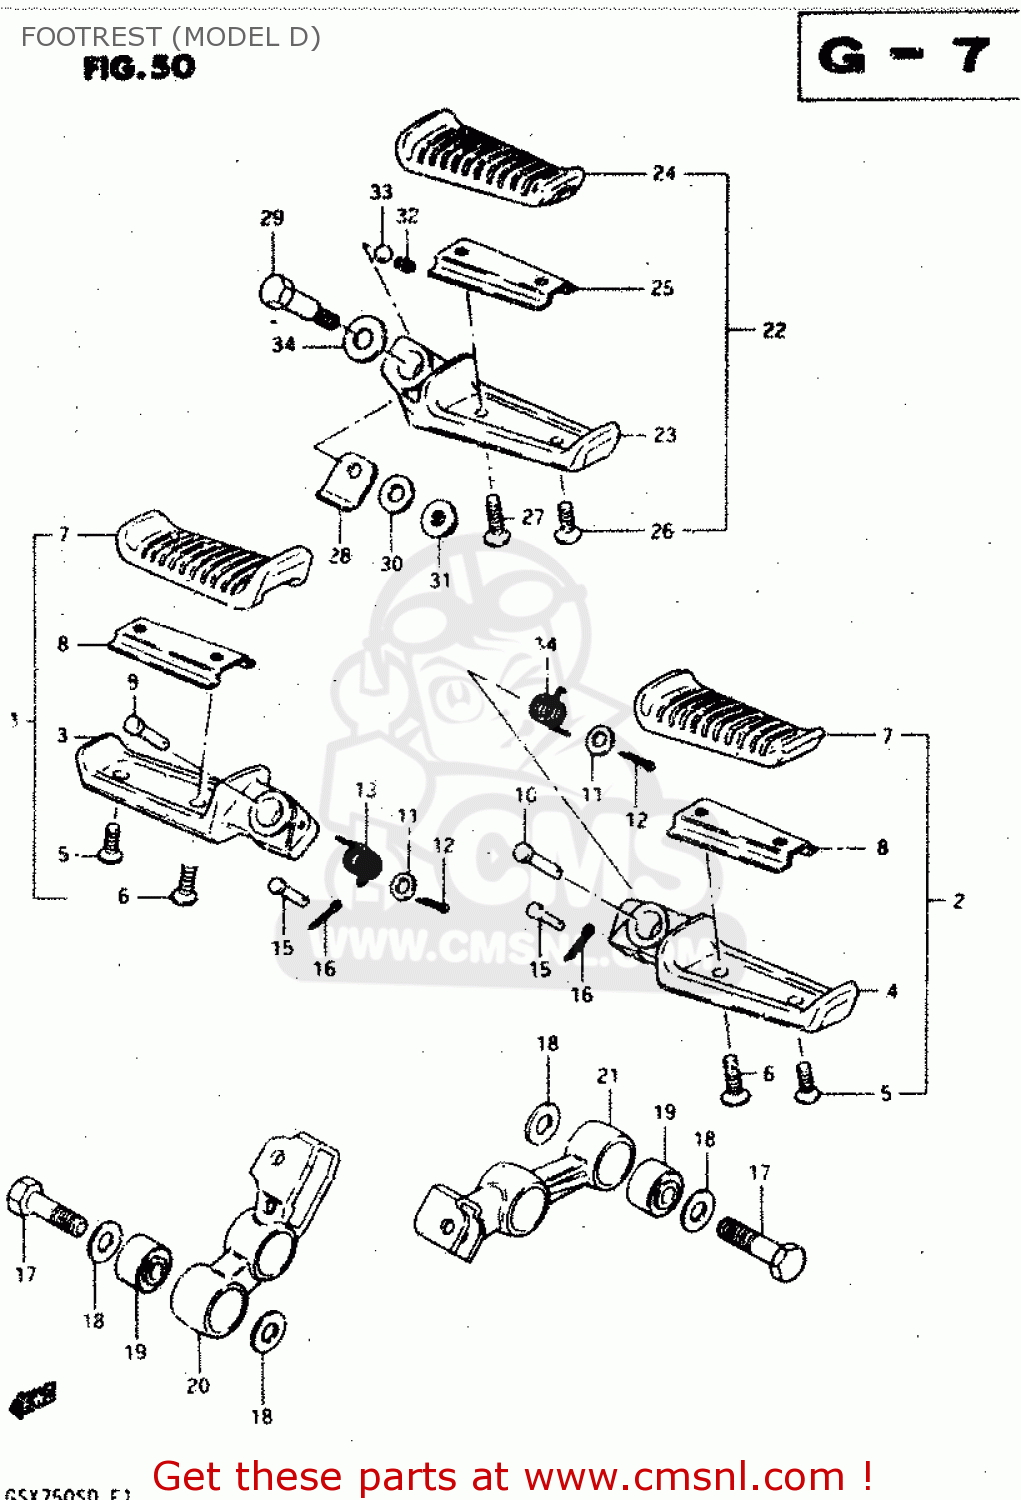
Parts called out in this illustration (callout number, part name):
1	FOOTREST ASSEMBLY,FRONT,RIGHT
2	FOOTREST ASSEMBLY,FRONT,LEFT
3	BAR,FRONT FOOTREST
4	BAR,FRONT FOOTREST,LEFT
5	SCREW
6	SCREW
7	RUBBER,FR FOOTREST
8	PLATE,FR FOOTREST RUBBER
9	PIN
10	PIN
11	WASHER
12	PIN 20X20
13	SPRING
14	SPRING
15	PIN
16	PIN 20X20
17	BOLT
18	WASHER
19	BUSH
20	HOLDER,FR FOOTREST,R
21	HOLDER,FR FOOTREST,L
22	FOOTREST ASSY,PILLION,R
23	BAR,PILLION FOOTREST,LEFT
24	RUBBER,PILLION FOOTREST
25	PLATE,RUBBER STOPPER
26	SCREW 5X12
27	SCREW
28	PLATE,SPRING STOP
29	BOLT(6X45)
30	WASHER
31	NUT
32	SPRING
33	BALL
34	SHIM(8.2X22X0.2)
